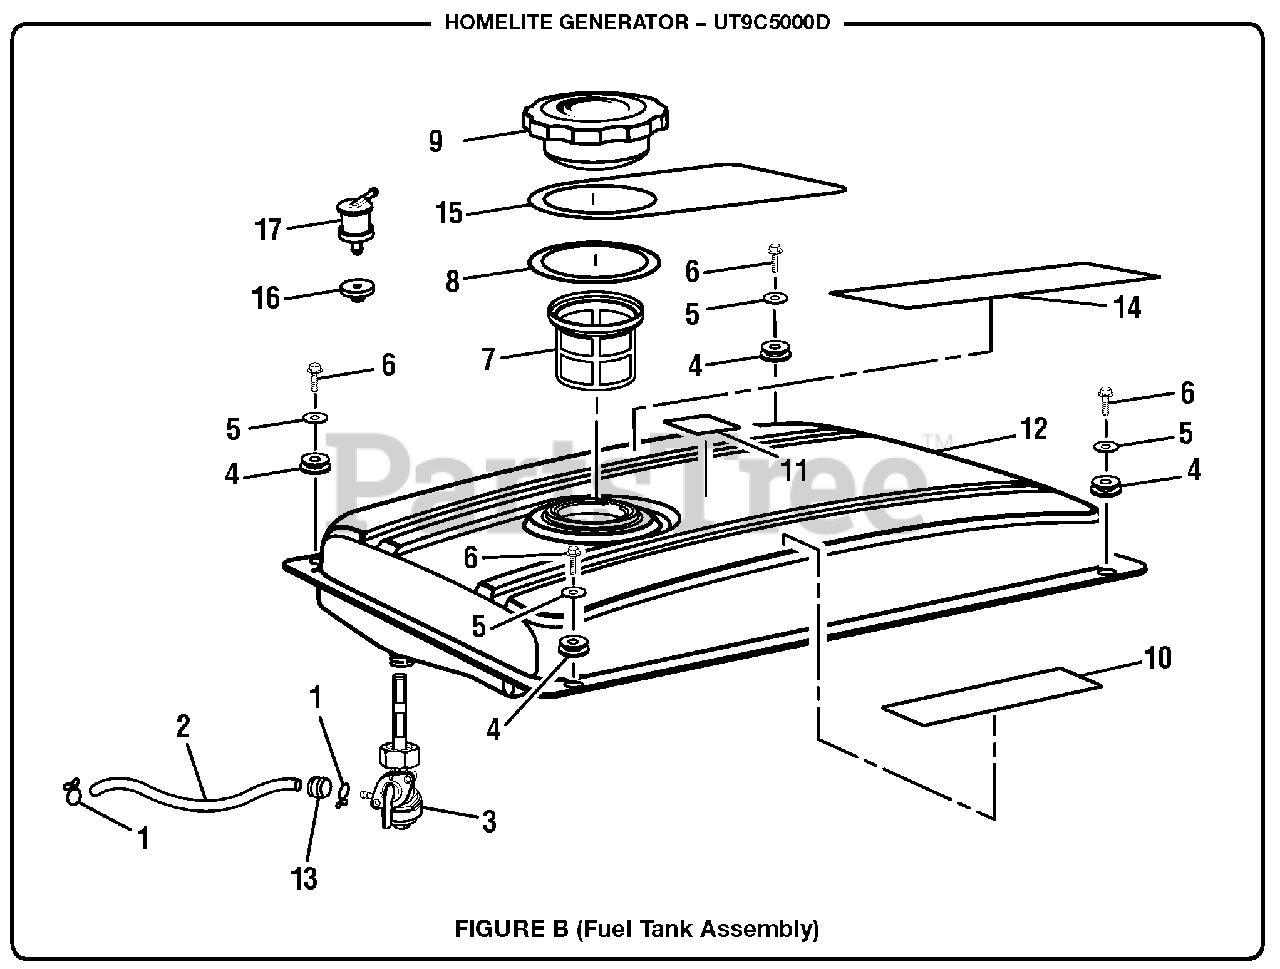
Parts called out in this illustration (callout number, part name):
1	Fuel Line Clamp
2	Fuel Line Hose
3	Fuel Valve Assembly
4	Bushing w/Insert
5	Washer (M6)
6	Bolt (M6 x 25 mm, Flange Hd)
7	Fuel Tank Screen
8	Gasket (Fuel Cap)
9	Fuel Cap Assembly
10	CPSC Label
11	E-85 Label
12	Fuel Tank
13	Grommet (Fuel Line)
14	Danger Label
15	Engine Warning Hang Tag
16	Check Valve Bushing
17	Check Valve
